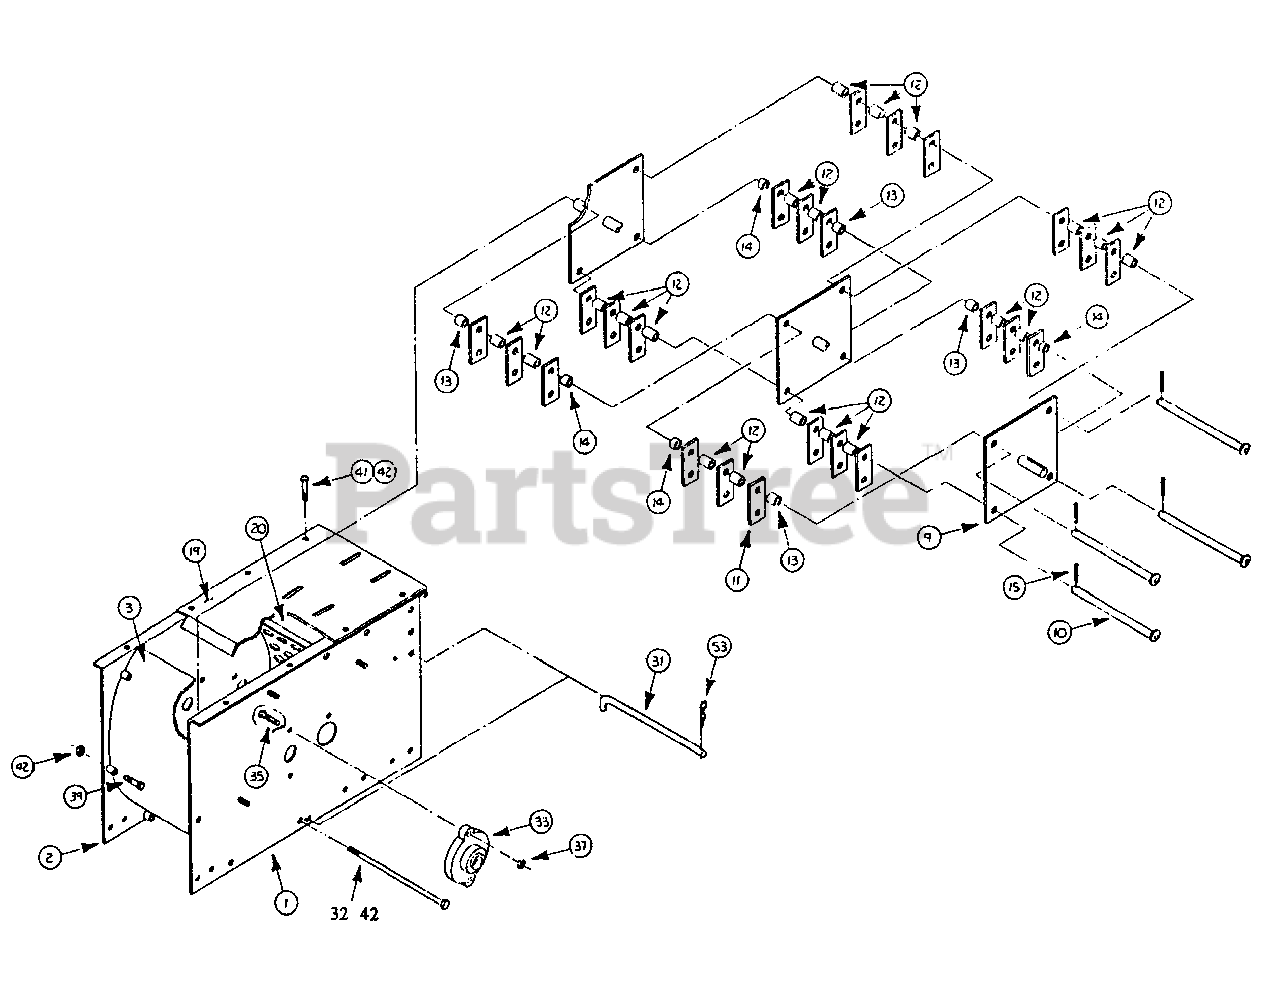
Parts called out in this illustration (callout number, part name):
1	Right Side Plate
2	Left Side Plate
3	Scroll
9	Rotor Weldment
10	Hammer Rod
11	Hammer
12	Spacer 7/8"
13	Spacer 5/8"
14	Spacer 5/16"
15	Groove Pin
19	Top Plate
20	Screen (1" Standard)
31	Screen and Baffle Rod
32	Tie Red
33	Bearing Right Side
35	3/8-16 x 1 Hex Hd. Cap Screw GR 5 Blk.
37	3/8-16 Grip-Co Lock Nut
39	5/16-18 x 1-1/4 Hex Hd. Cap Screw GR5
41	5/16-18 x 3/4 Hex Hd. Cap Screw GR 5
42	5/16-18 Grip-Co Lock Nut
53	3/32 Hair Cotter Pin
